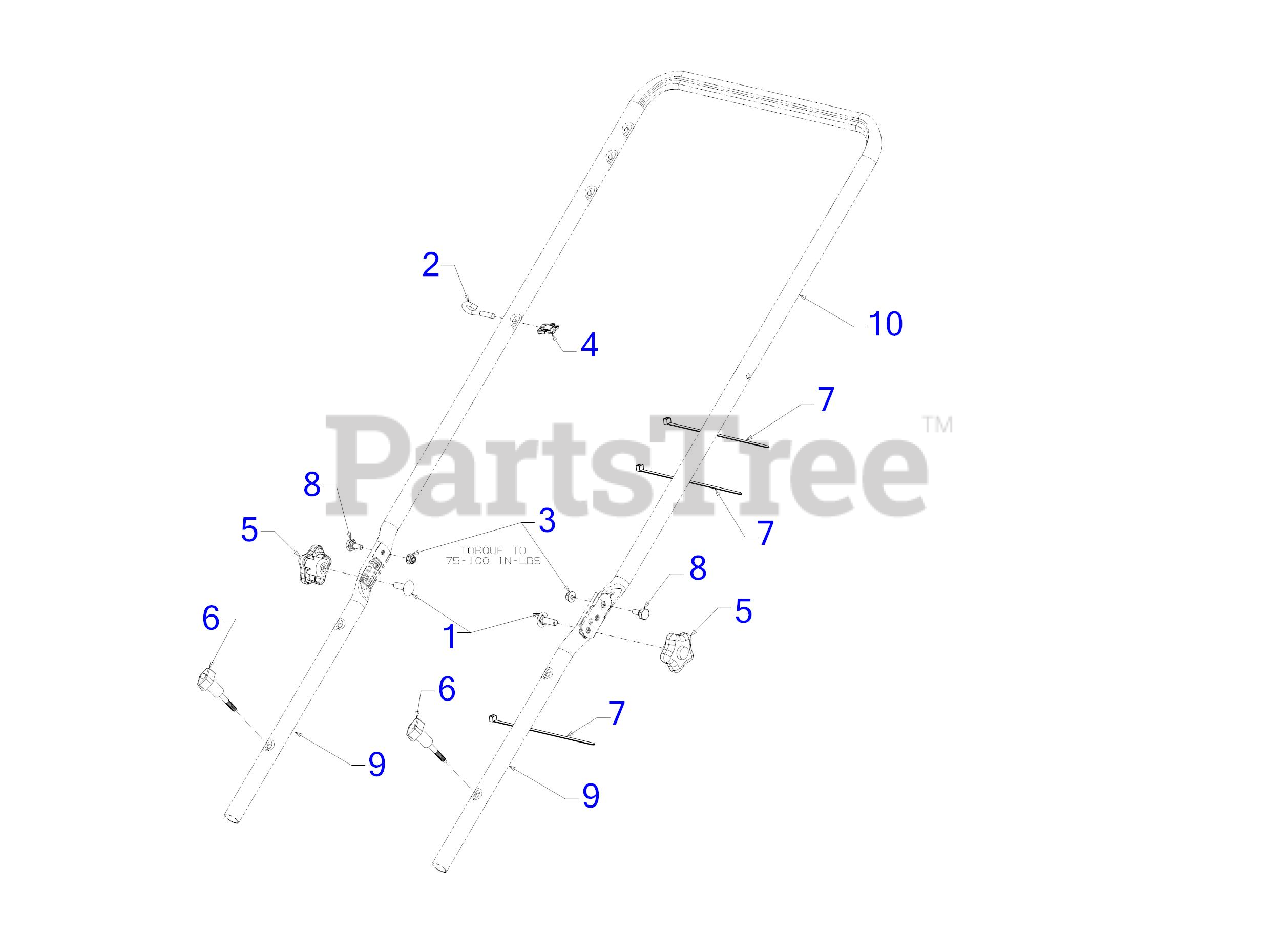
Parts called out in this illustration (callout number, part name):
1	SCREW 5/16-18 x 1.00 GR5
2	EYEBOLT 1/4-20
3	FLANGE LOCK NUT
4	HANDLE KNOB
5	STAR KNOB- YELLOW
6	WING KNOB 1/4-20
7	7" CABLE TIE
8	SHOULDER SCREW
9	LOWER HANDLE
